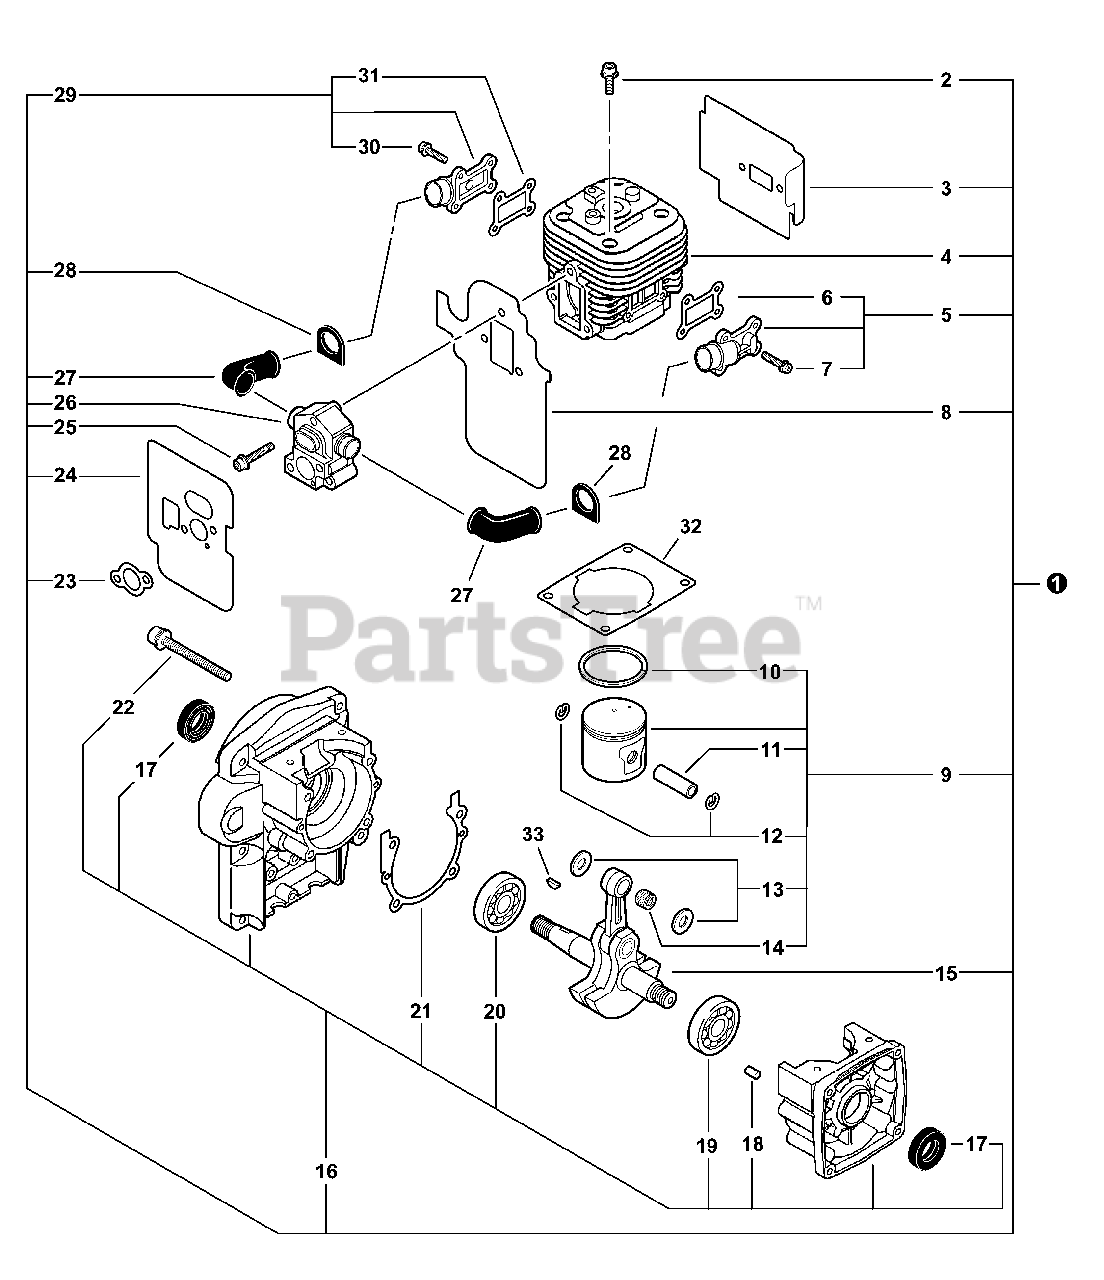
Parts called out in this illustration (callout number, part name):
1	SHORT BLOCK -- SB1095
2	SCREW - 5×22
3	SHIELD, EXHAUST
4	CYLINDER
5	REED VALVE KIT - OUTER
6	GASKET, INTAKE
7	SCREW - 4
8	GASKET, INTAKE
9	PISTON KIT
10	RING, PISTON
11	PIN, PISTON
12	RING, RETAINING - 8
13	WASHER - 10
14	BEARING, NEEDLE - 10
15	CRANKSHAFT ASSY
16	CRANKCASE KIT
17	SEAL, OIL
18	PIN - LOCATING
19	BEARING, BALL - 6202
20	BEARING, BALL - 6302
21	GASKET, CRANKCASE
22	SCREW - 5×40
23	GASKET, INTAKE
24	SHIELD, INTAKE
25	SCREW - 5×35
26	VALVE ASSY
27	HOSE, AIR
28	GROMMET
29	REED VALVE KIT - INNER
30	SCREW - 4
31	GASKET, INTAKE
32	GASKET, CYLINDER
33	KEY - 3×14
